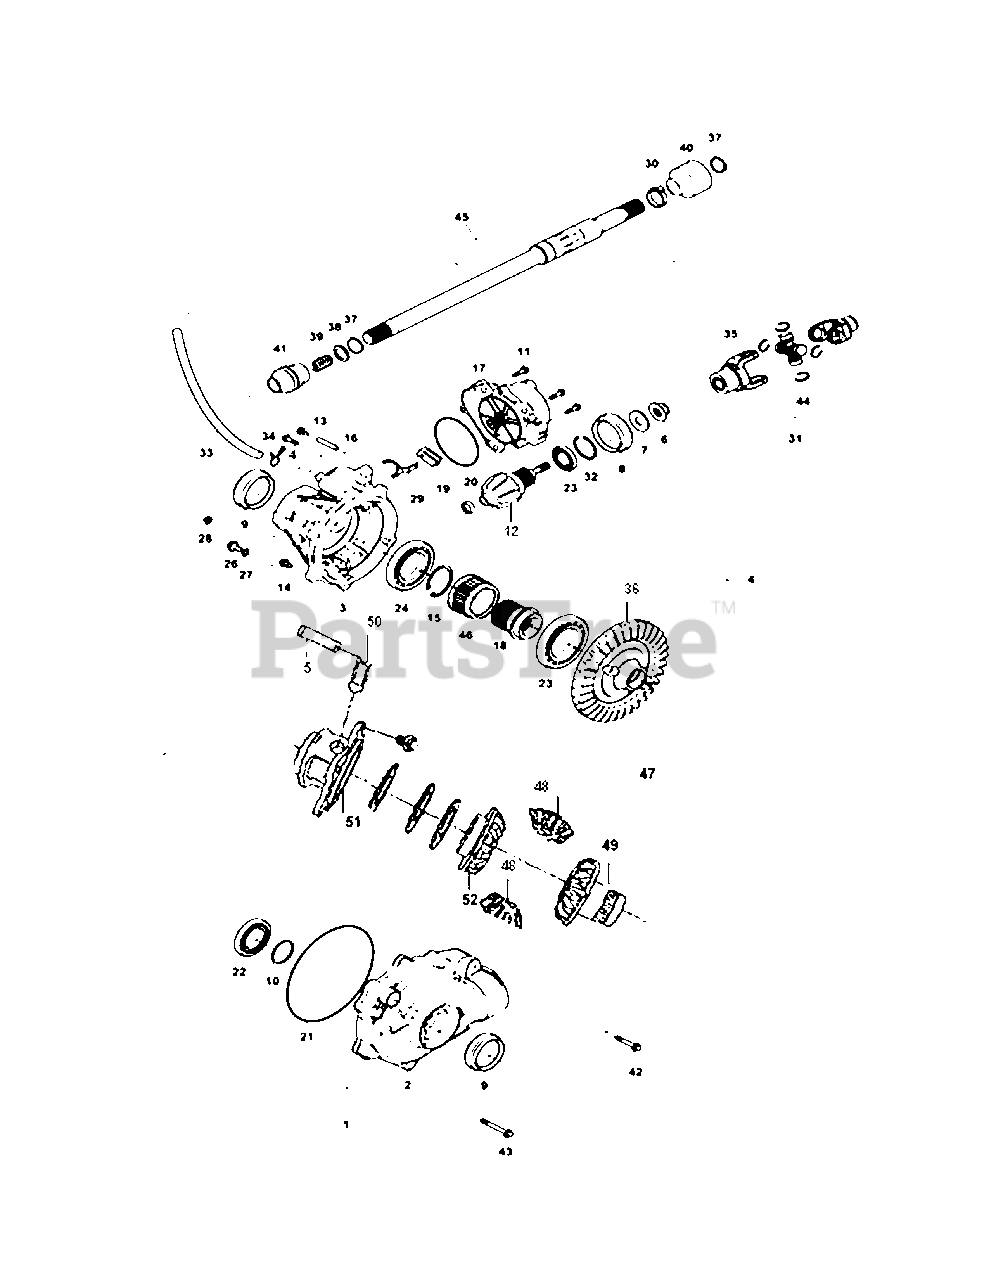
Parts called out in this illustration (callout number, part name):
1	Front Differential Assy
2	Front Differential Case II
3	Front Differential Case I
5	04 spring pin
7	O-Ring 6.8×14
8	Oil Seal48?65?9
9	Oil Seal24?38?8
10	Washer I 50?61.5
12	Front bridge driving gear
13	Socket Hexagon Screw M8×10
14	Bolt M10×1.25×16
17	Transfer Case Assembly
18	Divide Device Connection
20	O-Ring2×81,Transfer Case
21	O-Ring 2.62×139.37
22	Bearing 35×62×14
23	Bearing 60×85×13
24	Bearing 35×62×9
25	Bearing 15×21×12
26	Screw
27	O-Ring 13×1.5
28	Hexagon flange nut M10×1.25
29	Shaft Fork IV
30	Clamp20-32
31	Universal Joint I
32	Spring ring
33	Vent Pipe L=700
34	Oil Pipe Clip 8
35	Cross Axle
36	Front bridge driven gear
37	Circlip D0=19
38	Circlip20×26×1
39	Spring25?2.3?28
40	Front Dust Proof Cover, Front Middle Shaft
41	Rear Dust Proof Cover, Front Middle Shaft
42	Hexagon Flange Bolt M10×1.25×30
43	Hexagon Flange Bolt M10×1.25×142
44	Block Ring
45	Front Transmission Shaft Comp
46	Coupling sliding sleeve
47	Differencial Comp
49	Front left axle gear
50	Round pin 15X82
51	Front bridge differencial cover
